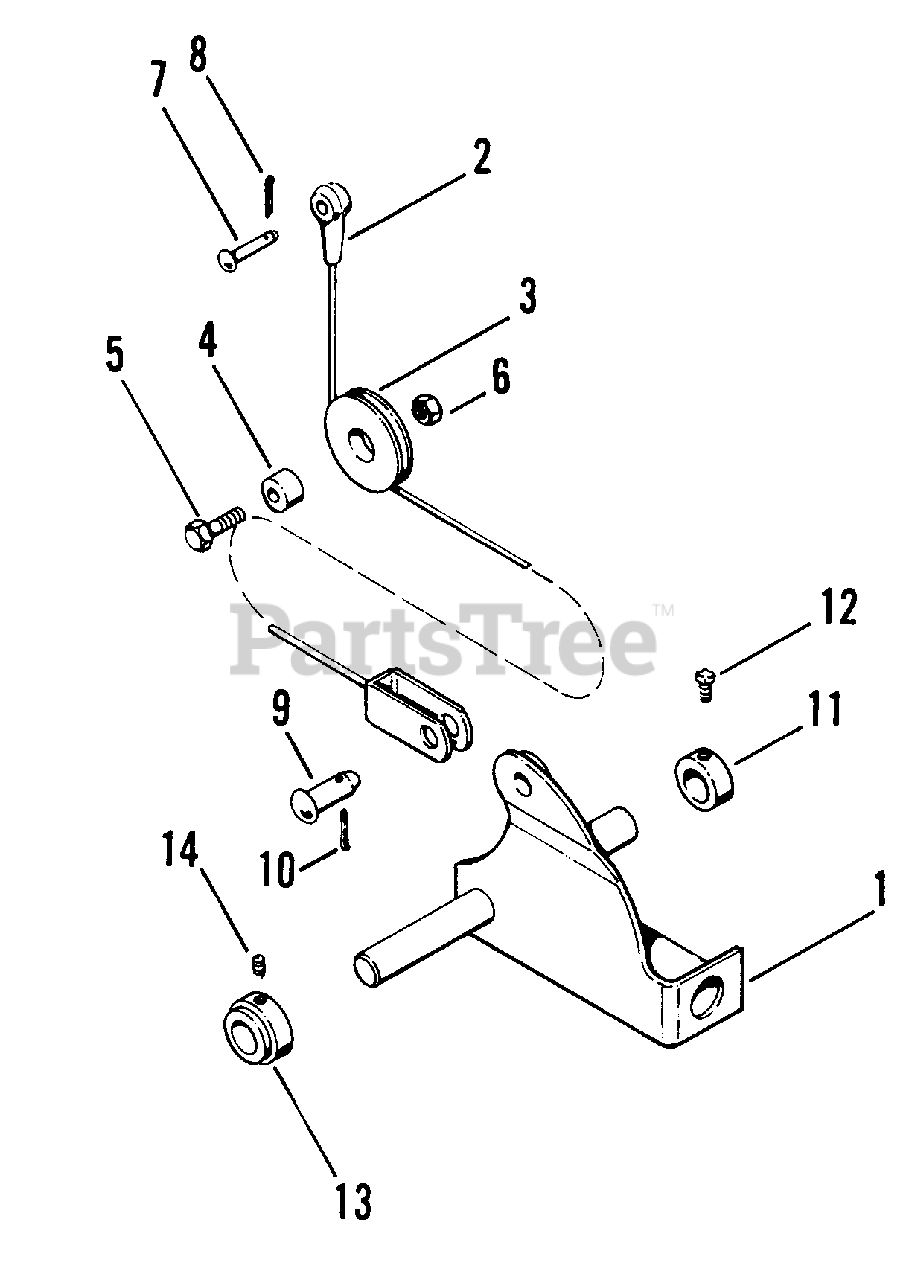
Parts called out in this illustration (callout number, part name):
1	Lift Lever Assembly
2	Lift Cable Assembly
5	Hex Capscrew, 3/8"-16 x 1-1/4" lg.
6	Hex Jam Nut, 3/8"-16
7	Pin
8	Cotter Pin, 3/32" x 7/8" lg
10	Cotter Pin, 1/8" x 1' lg.
11	Set Collar
12	Set Screw, 5/16"-18 x 3/8" lg.
14	Set Screw
